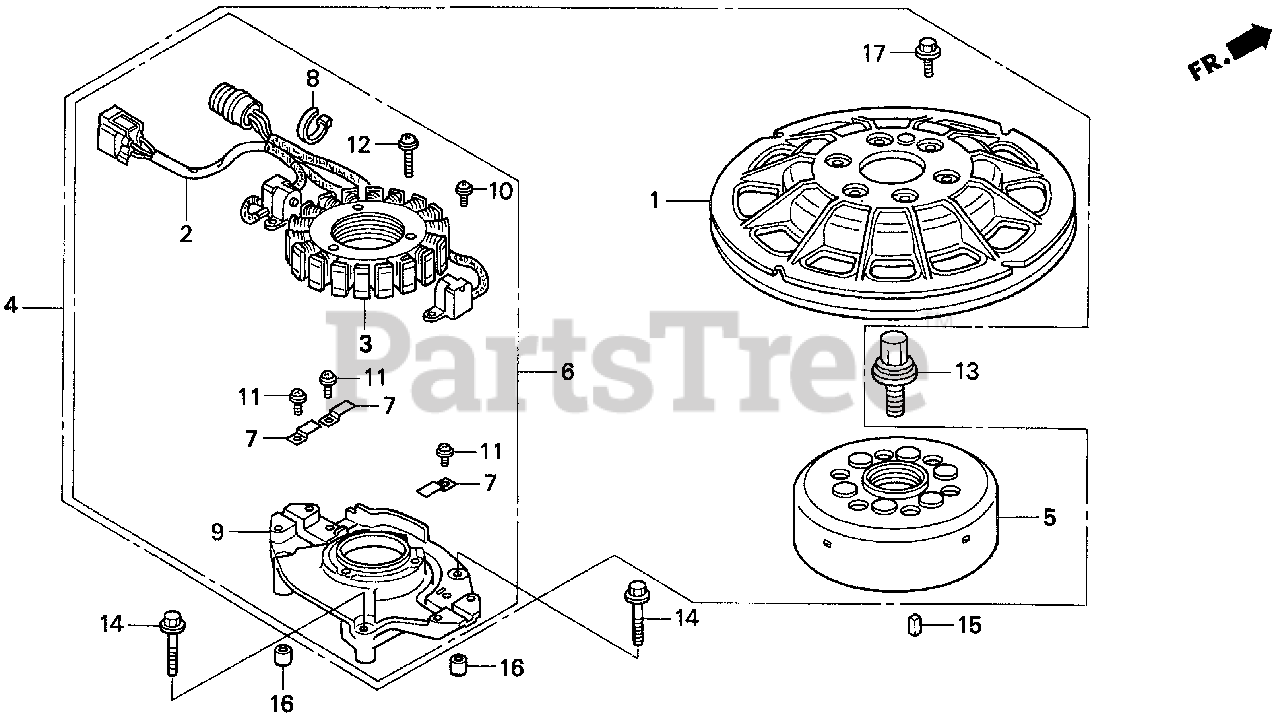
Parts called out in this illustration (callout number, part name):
1	PULLEY, STARTER
2	COIL ASSY., PULSER
4	ALTERNATOR ASSY.
6	STATOR ASSY.
7	CLAMP, WIRE
8	CLAMP, CABLE
9	BASE, COIL SETTING
10	SCREW-WASHER (5X12)
11	SCREW-WASHER (4X8)
12	SCREW-WASHER (6X30)
13	BOLT-WASHER (14X29)
14	BOLT, FLANGE (6X42)
15	KEY (4.5X11.0)
16	PIN A, DOWEL (8X10)
17	BOLT, FLANGE (6X18)
